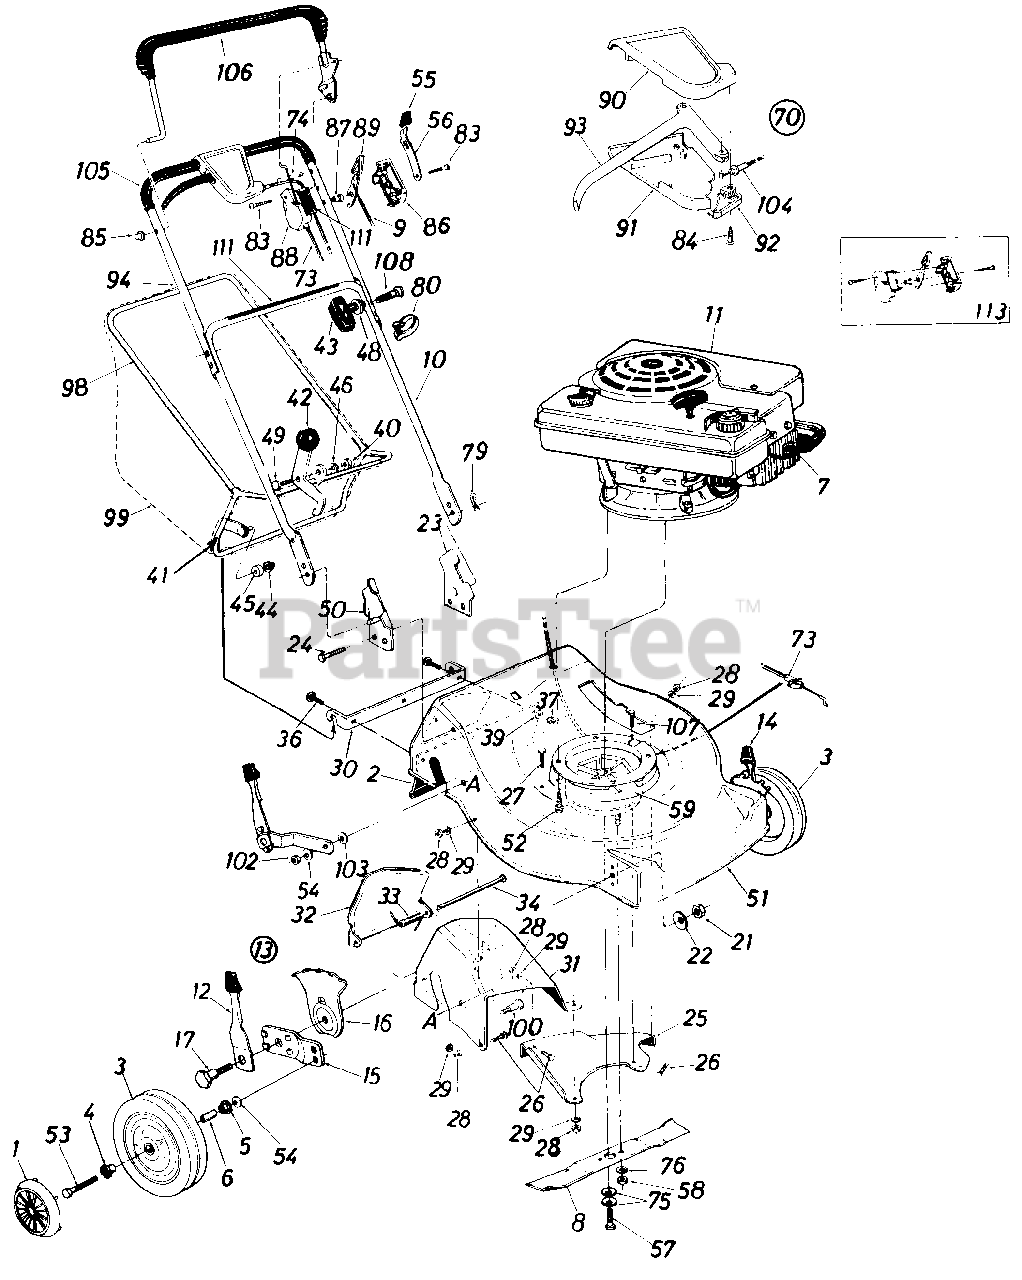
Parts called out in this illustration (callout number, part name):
1	Hub Cap Plastic
2	Rear Flap Ass'y.
3	Front Wheel Ass'y. Comp.
4	Bearing 3/8 I.D.
5	Bearing 112" I.D.
6	Spacer
7	Spark Plug Boot
8	20" Blade
9	Throttle Control Wire 43"
10	Lower Handle
12	Spring Lever Ass'y. w/Knob
13	Height Adjust. Ass'y. R.H.
14	Height Adjust. Ass'y. L.H.
15	Pivot Bar
16	Index Plate
17	Shld. Bolt .50" Dia. x .375"
21	Hex Nut 3/8-16 Thd.
22	Bell-Wash. .39" I.D. x 1.38" O.D.
23	Handle Brk't. Ass'y. L.H.
24	Hex Wash. Hd. A B-Tap Scr. 1/4" x .62" Lg.
25	Rear Baffle L.H.
26	Carriage Bolt 1/4-20 x .50"
27	Hex Bolt 1/4-20 x .88" Lg.*
28	Hex Nut 1/4-20 Thd.
29	L-Wash. 1/4" I.D.
30	Grass Catcher Hitch Brk't.
31	Rear Chute Baffle Ass'y.
32	Chute Door
33	Torsion Spring
34	Hinge Pin .250" Dia. 7.88" Lg.
36	Carriage Bolt 1/4-20 x .75"
37	Sems Nut 1/4-20 Thd.
39	Fl-Wash. .285" I.D. x 1.25"
40	Hex Nut 5/16-18 Thd.
41	Grass Catcher Lower Frame A ss'y.
42	Cam Lever Ass'y.
43	Hand Knob
44	Push Nut 3/8 Rod
45	Plastic Roller
46	L-Wash 5/16" I.D.
48	Bell-Wash. 5/16" I.D.
49	Shld. Bolt .437" Dia. x .180"
50	Handle Brk't. Ass'y. R.H.
53	Axle Bolt
54	Bell-Wash. .44" I.D. x .88"
55	Spring Lever Knob
56	Lockout Lever
57	Hex Bolt 3/8-24 x 2.00" Lg. (Grade 8)
58	Hex Nut 3/8-24 Thd. (Grade 8)
59	Blade Brake Clutch Ass'y. Comp.
70	Clutch Control Housing Comp.
73	Clutch Cable 46"
74	Lock Pin .314" Dia. x 1.70"
75	Bell-Wash. .44" I.D. x 88"
76	L-Wash. 3/8 I.D.
79	Intern. Cot. Pin 5/16" Dia.
80	Cable Tie
83	T-russ Mach. Scr. #12 x 1.50"
84	Flat "C"-Sunk Hd. Scr. #10 x 1.0" Lg.
85	Cap Speed Nut 5/16" Rod
86	Control Panel Half
87	Control Disc Pin
88	Clutch Panel Half
89	Throttle Control Lever
90	Control Cover Half Upper
91	Control Cover Half Lower
92	Cable Mtg. Cap
93	Control Lever
94	Upper Handle
98	Grass Catcher Upper Frame
99	Grass Bag
100	Shld. Bolt .500" Dia. x .685"
102	Hex Jam Nut 3/8-16 Thd.
103	Bell-Wash. .400" I.D.
104	Clutch Cable 50"
106	Blade Clutch Control Handle
107	Hex Wash. Hd. Self-Tap Scr. 1/4-20 x .75" Lg.
108	Curved Hd. Carr. Bolt 5/16-18 x 1.751'
111	Control Labels
113	Control Housing Comp.
